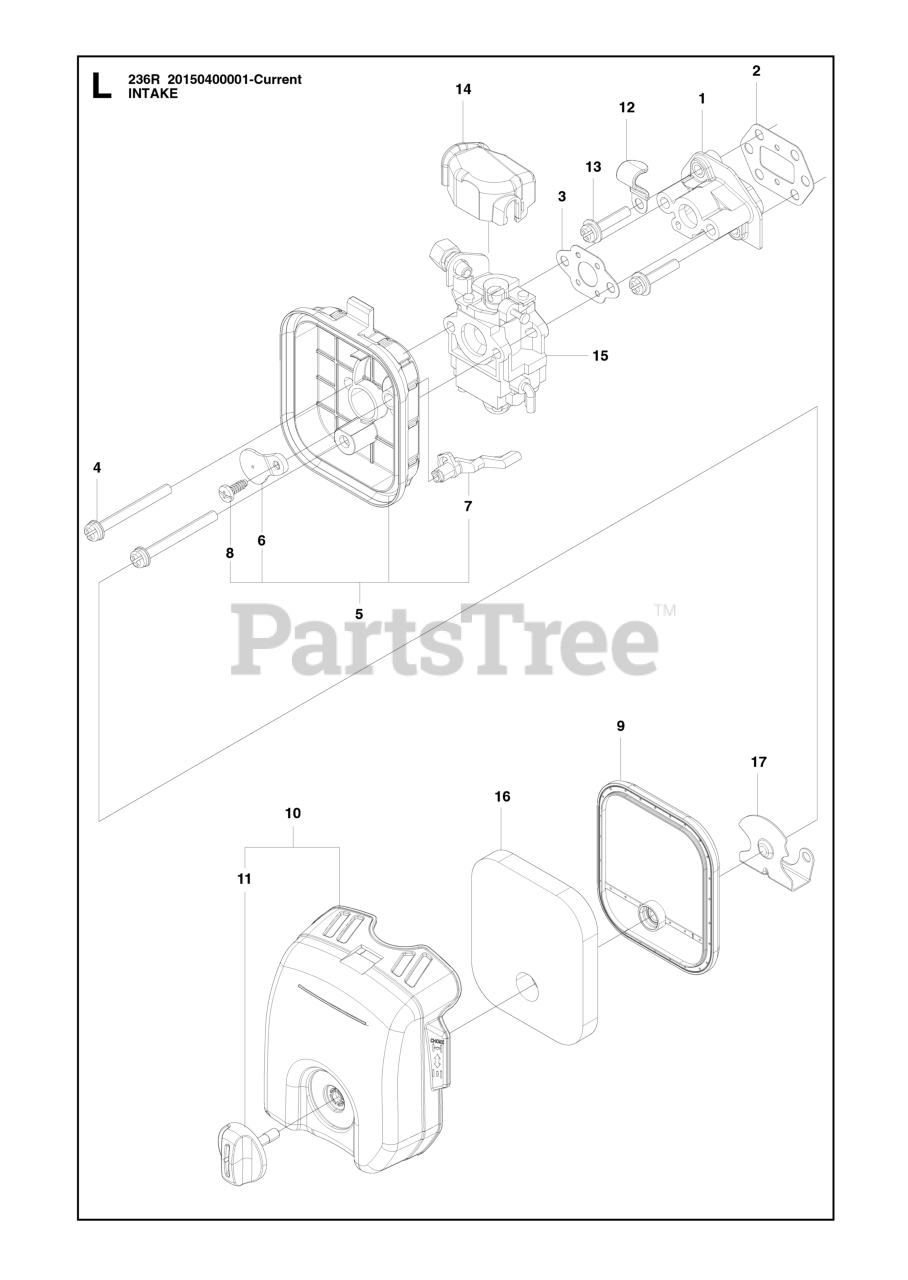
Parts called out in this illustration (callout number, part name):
6	PLATE, CHOKE
7	LEVER.CHOKE
8	SCREW
12	CLAMP
